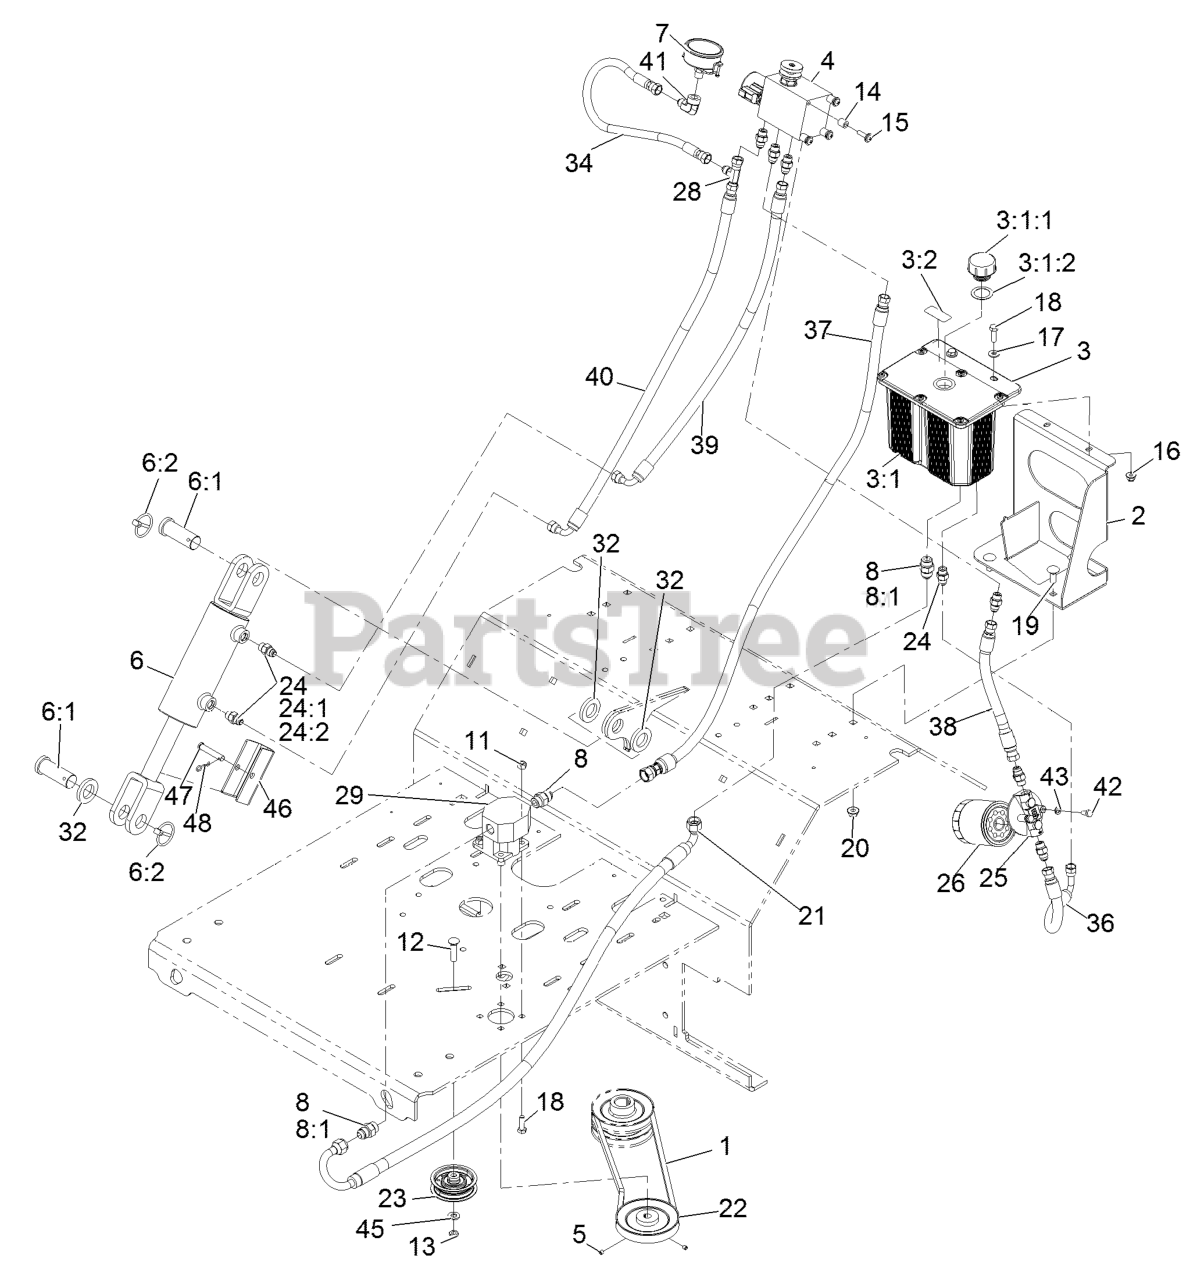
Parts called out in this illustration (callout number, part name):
2	BRACKET-TANK, HYDRAULIC
3	ASM-RESERVOIR W/DECAL
3:1	Tank-Hydraulic
3:1:1	Cap-Reservoir, HYD
3:1:2	GASKET-CAP
3:2	DECAL-HYDRO OIL AW-32
5	SCREW-SET, HSH
6	HYD CYLINDER ASM
6:1	PIN-CLEVIS
6:2	PIN-LYNCH
7	GAUGE-PRESSURE
8	FITTING-STRAIGHT
8:1	O-RING
11	NUT-LOCK, NI
12	SCREW-CARR
15	SCREW-PPH
16	NUT-HF, NI
17	WASHER-FLAT
18	SCREW-HH
19	BOLT-CARR
20	NUT-HF, NI
21	HYD HOSE ASM
23	PULLEY-IDLER, FLAT
24	FITTING-STRAIGHT
25	HEAD-FILTER
26	FILTER-25 MICRON, BI-DIRE
28	FITTING-HYD, TEE
29	PUMP-GEAR
34	HOSE ASM-HYD HP
36	HOSE-HYDRAULIC, LP
37	HOSE ASM-HYD HP
38	HOSE ASM-HYD
39	HOSE-HYDRAULIC
40	HOSE-HYDRAULIC, HP
41	FITTING-ELBOW, 90
42	SCREW-HH
43	WASHER-LOCK
45	WASHER-FLAT
46	STOP-CYLINDER
47	PIN-CLEVIS
48	PIN-COTTER
